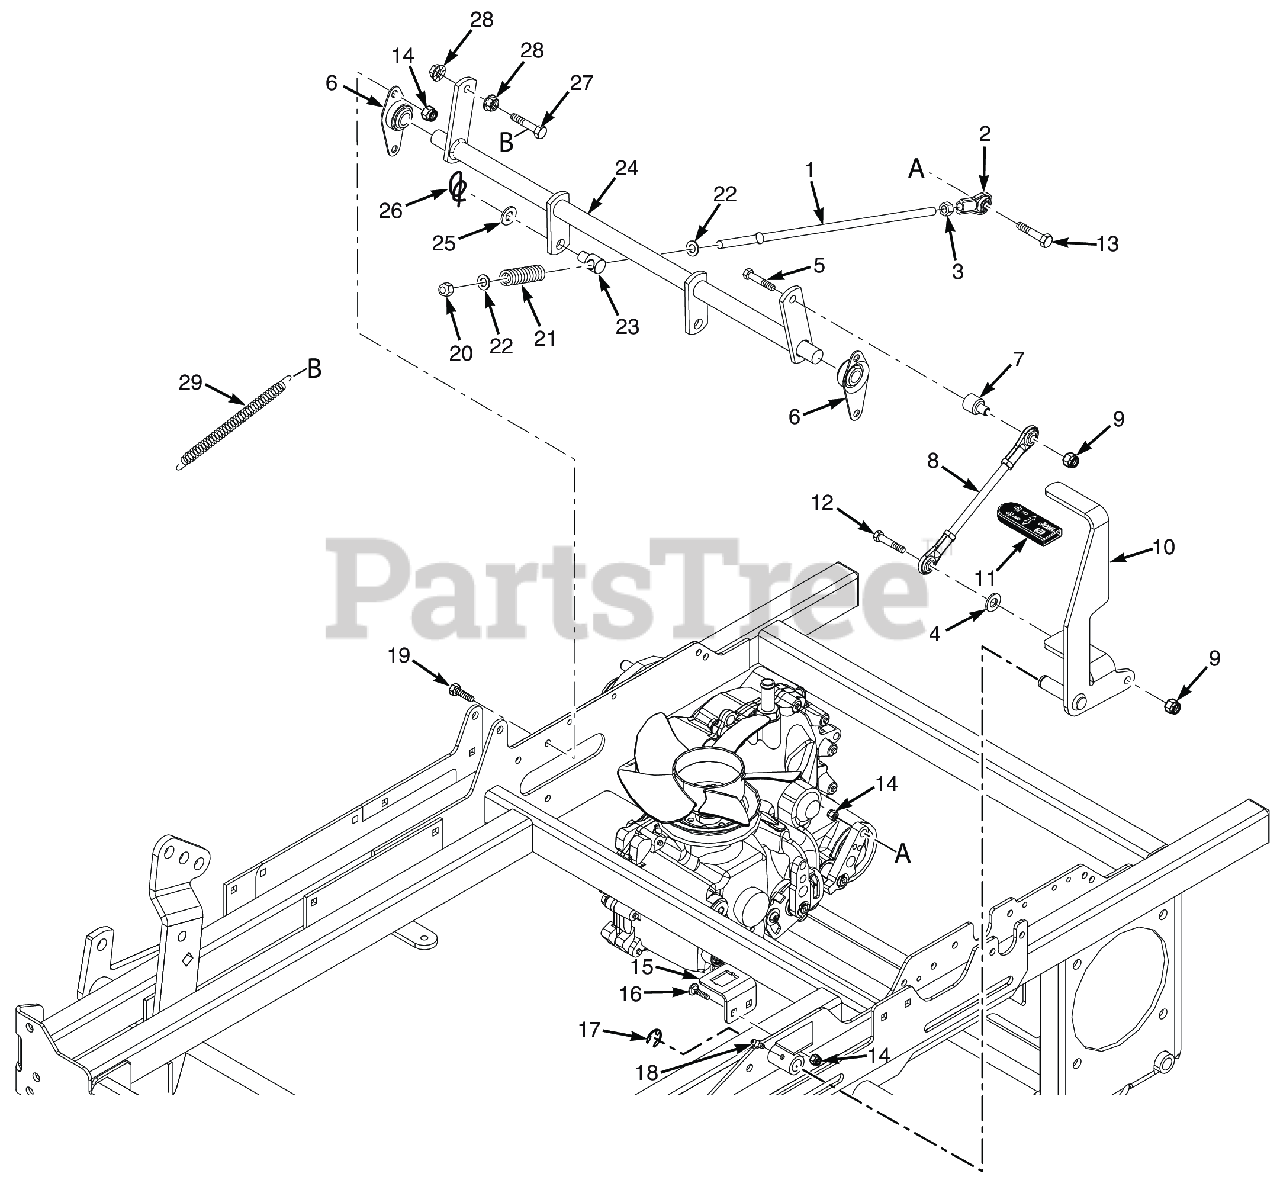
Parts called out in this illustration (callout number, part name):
1	Rod, Brake Linkage
2	Rod End, 3/8-24
3	HEX NUT, 3/8-24 R.H. THREAD
4	Flatwasher, 3/8 (.391 x .938 x .105 HD) Grade 8
5	Capscrew, Hex Head 3/8-16 x 2.75"
6	Bearing, Self Align
7	Pivot, Idler - Short
8	LINKAGE ASSY, UPPER BRAKE
8	Rod End, 3/8-24 UNF RH
8	Nut, 3/8-24 UNF R.H. Thread
8	Rod End, 3/8-24 UNF LH
8	Nut, 3/8-24 UNF-2B LH Thread
9	HEX NUT, ELASTIC STOP LOCK, 3/8-16
10	Brake Lever w/Grip
11	Grip, Parking Brake
12	Bolt, Hex Head, 3/8-16 x 1-1/2"
13	Bolt, Hex Head 5/16-18 x 2-1/2" (x3) (35BV & 37BV-EFI)
14	Nut, Flange Head Elastic Stop 5/16-18
15	Bracket, Brake Switch
16	Bolt, 5/16-18 x .75 RHSN Carriage
17	RETAINING RING, 5/8" EXTERNAL "E"
18	GREASE FITTING, STR. 1/4-28 SELF TAP.
19	BOLT, SERRATED FLANGE HEX HEAD 5/16-18 X 3/4"
20	Nut, Elastic Stop 3/8-16, grade 8 black
21	Spring
22	FW, .375-.376/.380 X .734 X .063
23	BUSHING, PIVOT SLIDE
24	Weldment, Brake Linkage
25	Flatwasher, 3/8 (.391 x .938 x .105 HD) Grade 8
26	Pin, Rue Cotter 1/2" Dia.
27	Bolt, Hex Head 3/8-16 x 1-1/2" Grade 8 Black
28	NUT, 3/8-16 SERRATED FLANGE HEX HEAD
29	Spring
